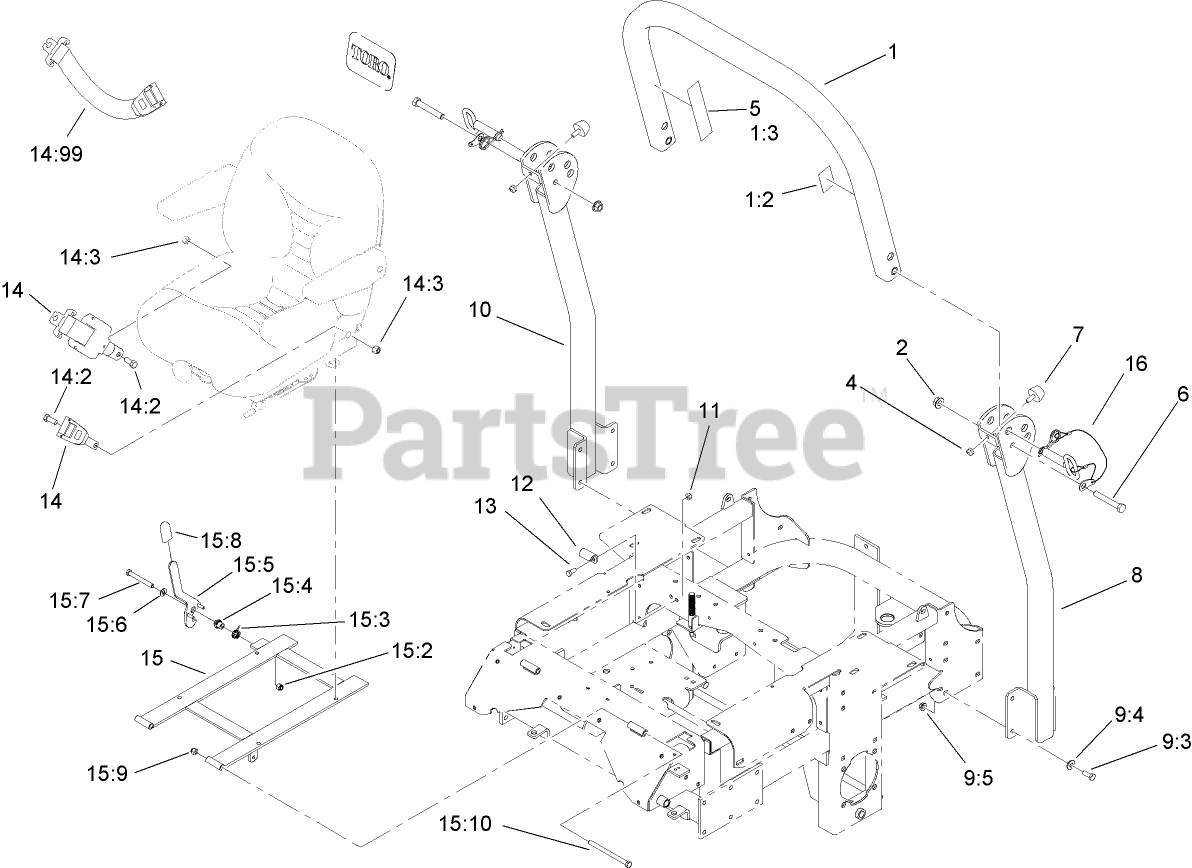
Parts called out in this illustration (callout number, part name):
1	Upper Tube ASM
1:2	DECAL-ROPS
1:3	DECAL-WARNING, FOLDING ROPS
2	NUT-HF
4	NUT-LOCK, NI
5	DECAL-WARNING
6	SCREW-HH
7	BUMPER-RUBBER
8	TUBE-SUPPORT, LH
9:3	SCREW-HH
9:4	WASHER-BELLEVILLE
9:5	NUT-HHF, WHIZ
10	TUBE-SUPPORT, RH
11	NUT-LOCK, NI
12	Catch-Latch, Seat
13	SCREW-HH
14	RETRACTABLE SEATBELT KIT
14:2	SCREW-HH
14:3	NUT-LOCK
14:99	SEAT BELT EXTENSION KIT
15	SEATFRAME ASM
15:2	NUT-LOCK, NI
15:3	SPRING-TORSION
15:4	BUSHING-LATCH, SEAT
15:5	LATCH ASM
15:6	WASHER-FLAT
15:7	SCREW-HH
15:8	GRIP-LEVER
15:9	NUT-LOCK, NI
15:10	SCREW-HH
16	PIN-FOLD, ROPS
